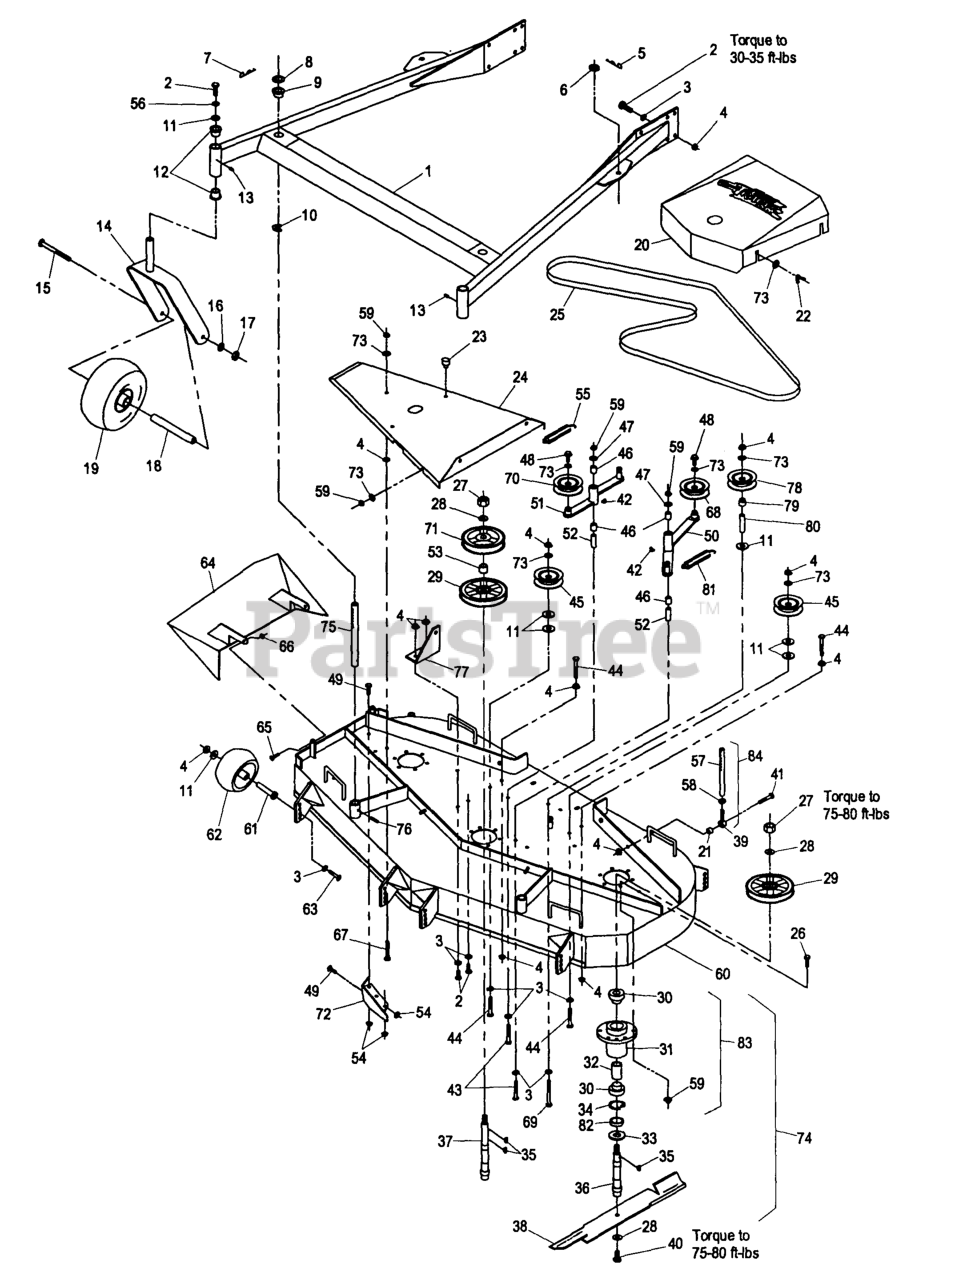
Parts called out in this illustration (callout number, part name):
1	SUPPORT ASSY-FMD60
5	PIN,HAIR COTTER
8	SPACER-DECK SUPPORT
9	BUSHING-DECK
11	WASHER
12	BEARING-FLANGED
22	NUT-WING
24	WLD,DECK COVER
25	BELT-DRIVE, BLADE
28	WASHER-SPRING
29	SHEAVE,BLADE DRIVE
30	BEARING
32	SPACER-BEARING
33	GUARD-BEARING, BOTTOM
36	SHAFT,SPINDLE SHORT
37	SHAFT,SPINDLE LONG
39	BALLJOINT
43	SCREW-HH
45	IDLER,PULLEY
46	SLEEVE-BEARING
50	Arm, Deck Drive Idler
51	Arm, Deck Idler
52	BUSHING-PIVOT, IDLER
53	SPACER-TUBE
55	SPRING-EXTENSION
57	LINK, DECK SUPPORT
61	BUSHING-ROLLER
62	ROLLER-SCALP, ANTI
68	PULLEY-IDLER
70	IDLER,PULLEY
72	WLD,BAFFLE DISCHARGE
74	CUTTER HOUSING ASM,OUTER
75	ROD,DECK SUPPORT
77	BRACKET,SPRING ANCHOR
78	PULLEY-IDLER
79	BUSHING,IDLER
80	SPACER-FENDER
81	SPRING-EXTENSION
